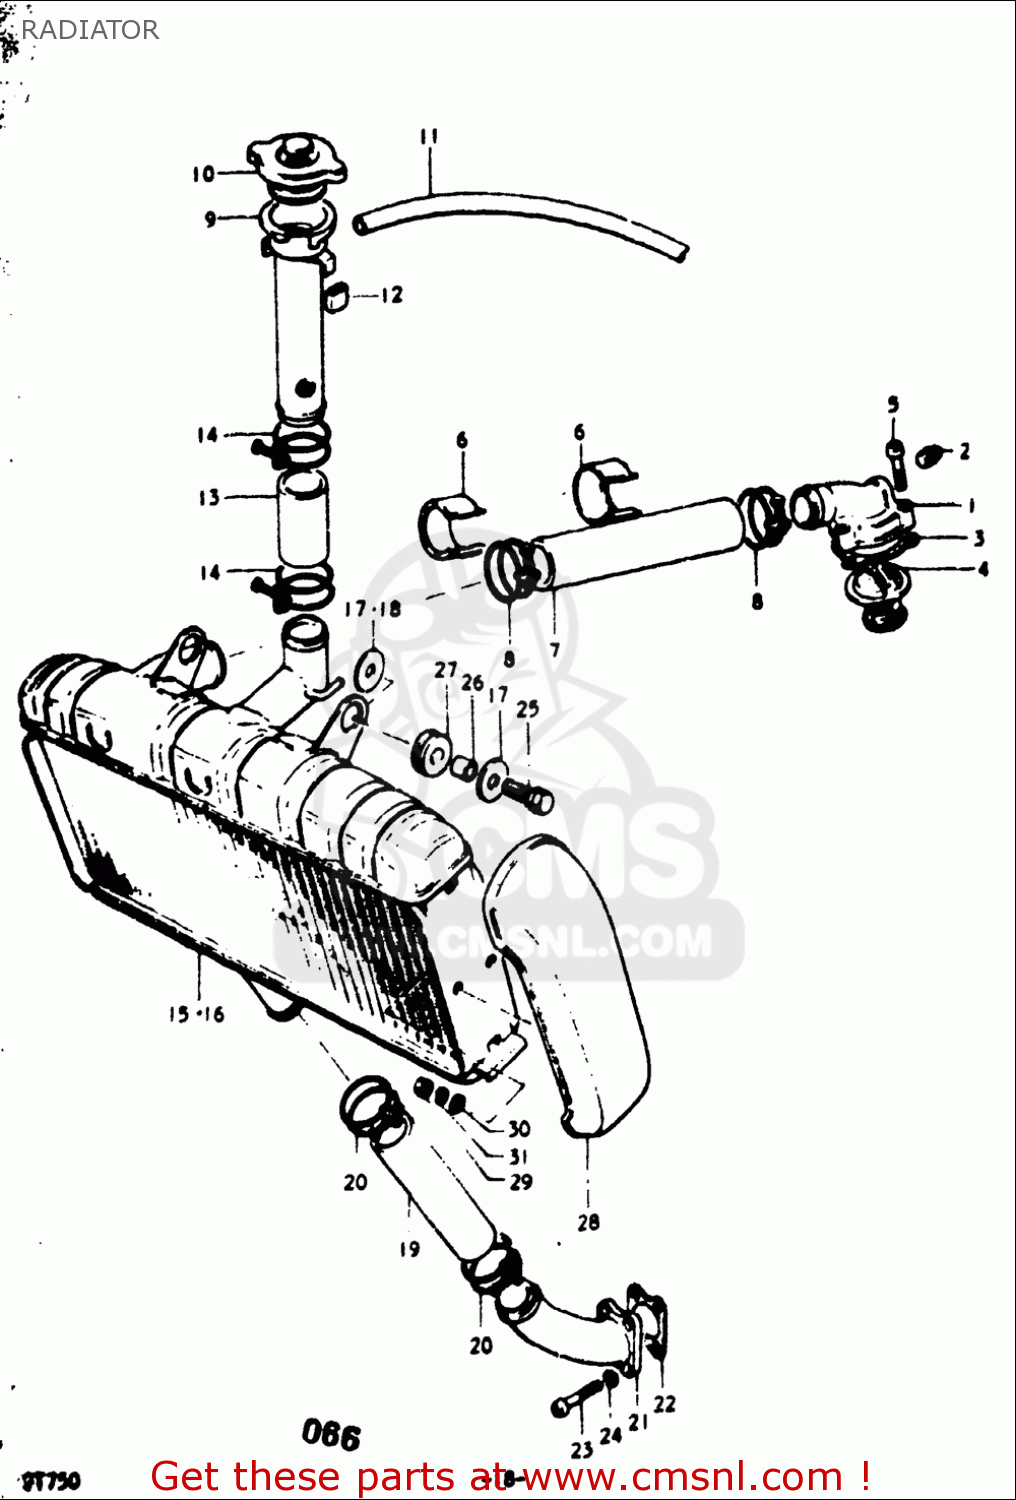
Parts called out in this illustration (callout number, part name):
3	GASKET,THERMOSTAT COVER (NAS)
4	THERMOSTAT,WATER
5	SCREW
7	HOSE(31X39X215)
8	CLAMP
10	CAP,RADIATOR 0.9
12	CUSHION
13	HOSE(31X39X215)
14	CLAMP
17	WASHER(8.5X28X1.6)
19	HOSE(31X39X215)
20	CLAMP
22	HOSE,WATER
23	SCREW
24	WASHER,LOCK
25	BOLT
26	SPACER,8.5X14X9
27	CUSHION
29	NUT
30	WASHER
31	WASHER,LOCK
